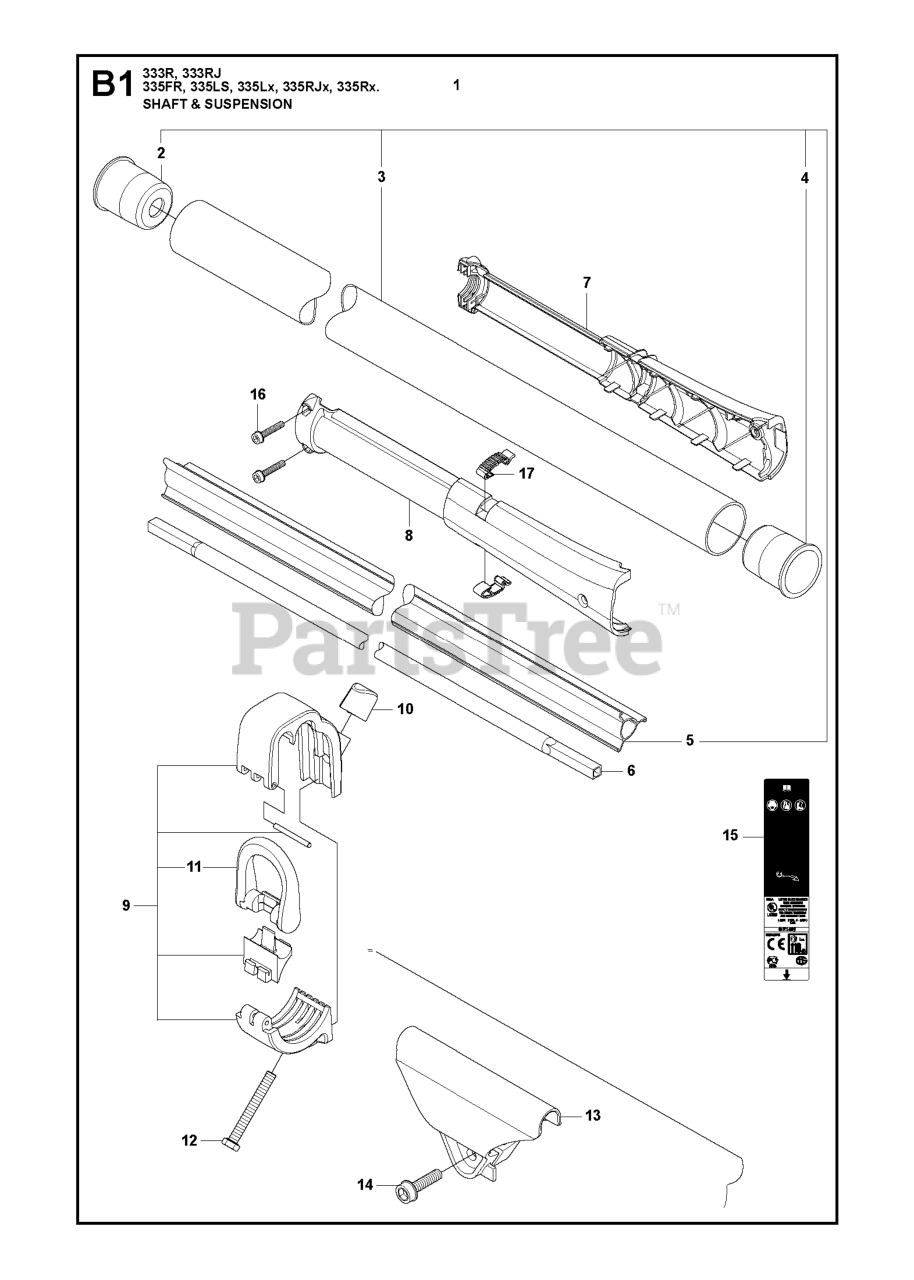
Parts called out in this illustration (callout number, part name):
1	TUBE
2	PLUG
3	TUBE
5	GUIDE
6	SHAFT
7	WEAR PROTECTION RIGHT
8	WEAR PROTECTION LEFT CPL
12	SCREW M6S 5X40
13	CABLE HOLDER
15	RP WARNING DECAL
